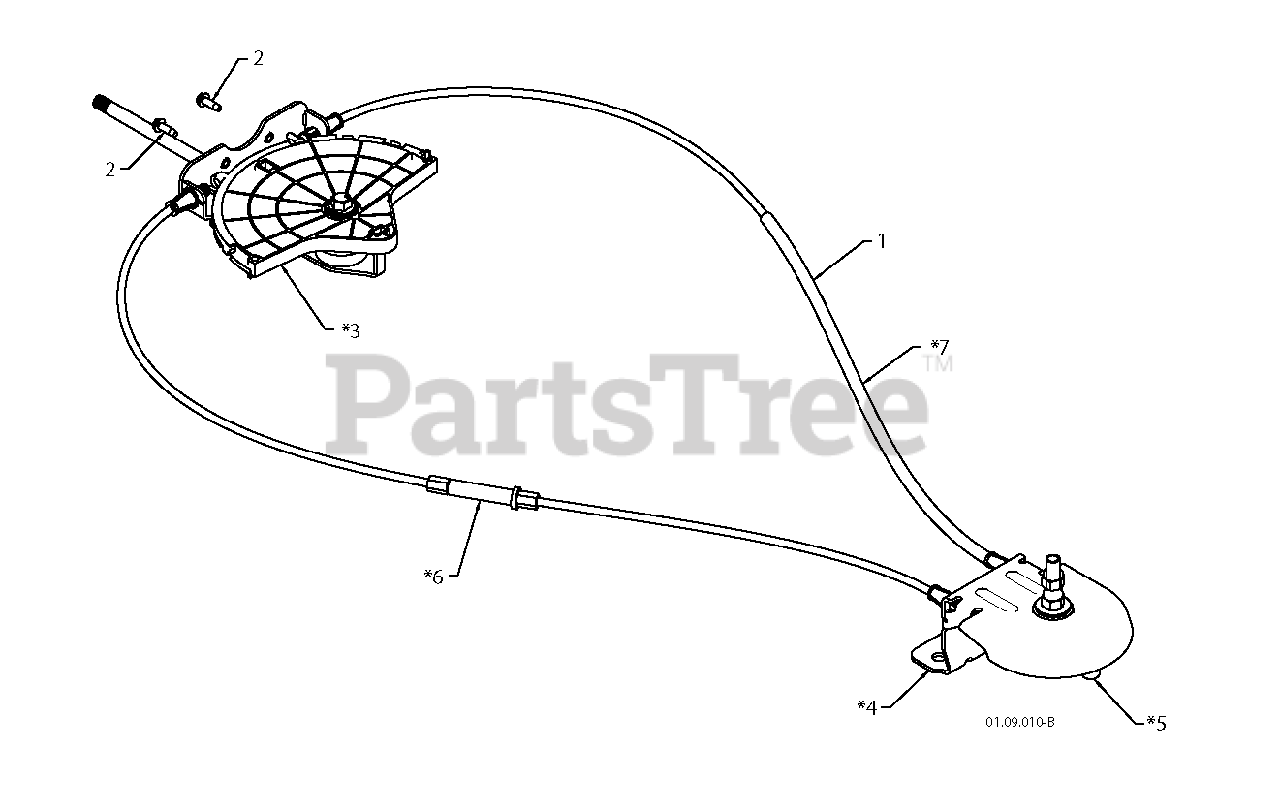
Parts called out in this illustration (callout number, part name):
1	LEVER/CABLE.ASM.ROTATOR
2	SCREW #10-24 X 5/8
3	CHUTE.ROT.HEAD.SERVICE
4	SNOW.PIVOT.BRKT.BLK.SERVICE
5	SNOW.PIVOT.PULLY
6	SNOW.CBL.ASM.ADJ.SERVICE(74)
7	SNOW.CBL.ASM.SERVICE(428272)
